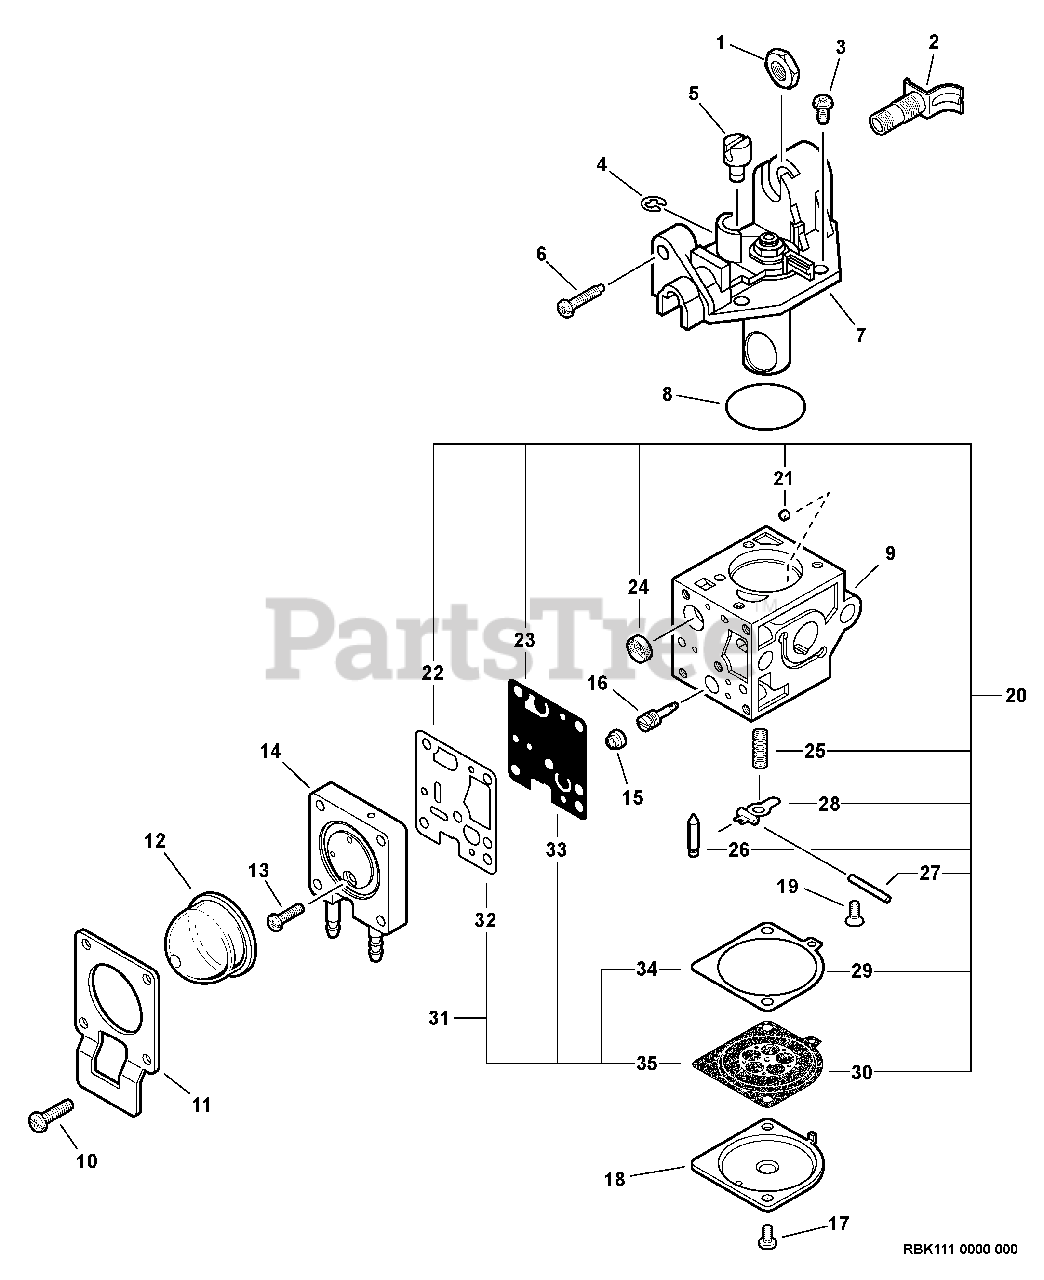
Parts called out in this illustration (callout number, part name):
2	GUIDE, CABLE
4	RING, RETAINING
6	SCREW, IDLE ADJUST
7	ROTOR COVER ASSY
9	BODY, CARBURETOR
10	SCREW, RETAINER
11	RETAINER, PURGE BULB
12	BULB, PURGE
13	SCREW, PURGE BASE
14	BASE, PURGE
15	CAP, LIMITER
16	NEEDLE - HIGH SPEED
18	COVER, METERING
19	SCREW, METERING LEVER PIN
20	REPAIR KIT
21	GUIDE, ROLLER
22	GASKET, PUMP
23	DIAPHRAGM, PUMP
24	STRAINER
25	SPRING, METERING LEVER
26	VALVE, INLET NEEDLE
27	PIN, METERING LEVER
28	LEVER, METERING
29	GASKET, DIAPHRAGM
30	DIAPHRAGM, METERING
31	DIAPHRAGM/GASKET KIT
32	GASKET, PUMP
33	DIAPHRAGM, PUMP
34	GASKET, DIAPHRAGM
35	DIAPHRAGM, METERING
